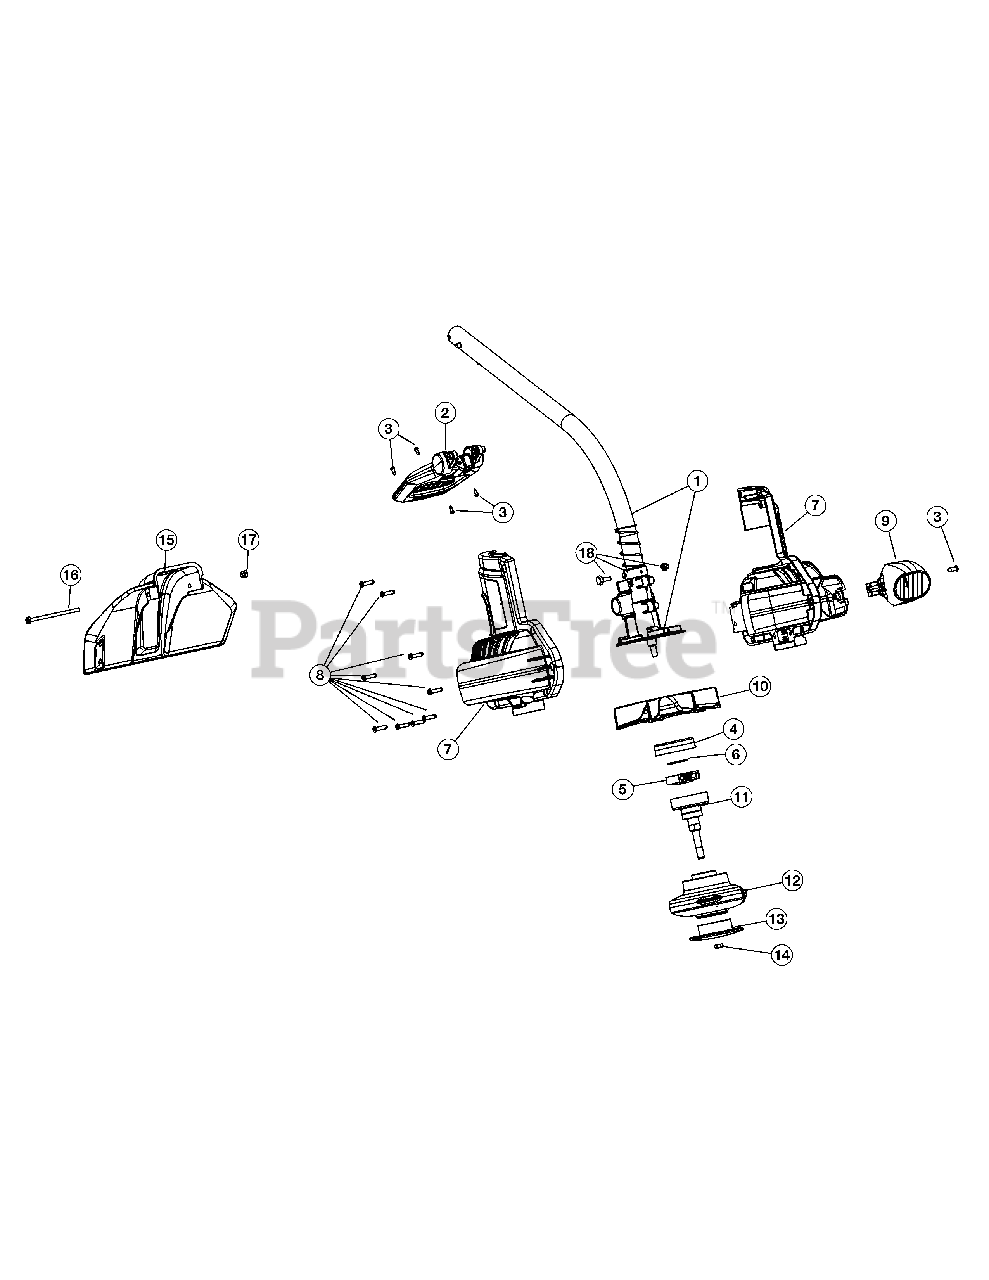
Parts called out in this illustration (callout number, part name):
1	Lower Drive Shaft Housing Assembly (Incl. Ref No. 18)
2	Shift Handle Assembly (Incl. Ref No. 3)
3	Screw
4	Clutch Drum Container
5	Clutch Assembly
6	Washer
7	Housing Assembly (Incl. Ref No. 8)
9	Nozzle
10	Impeller
11	Clutch Drum Assembly w/Spool Shaft
12	Fixed Line Head (Incl. Ref No. 13 & 14)
13	Glide Cap
14	Locknut
15	Guard Assembly w/Blade (Incl. Ref No. 16 & 17)
17	Nut
